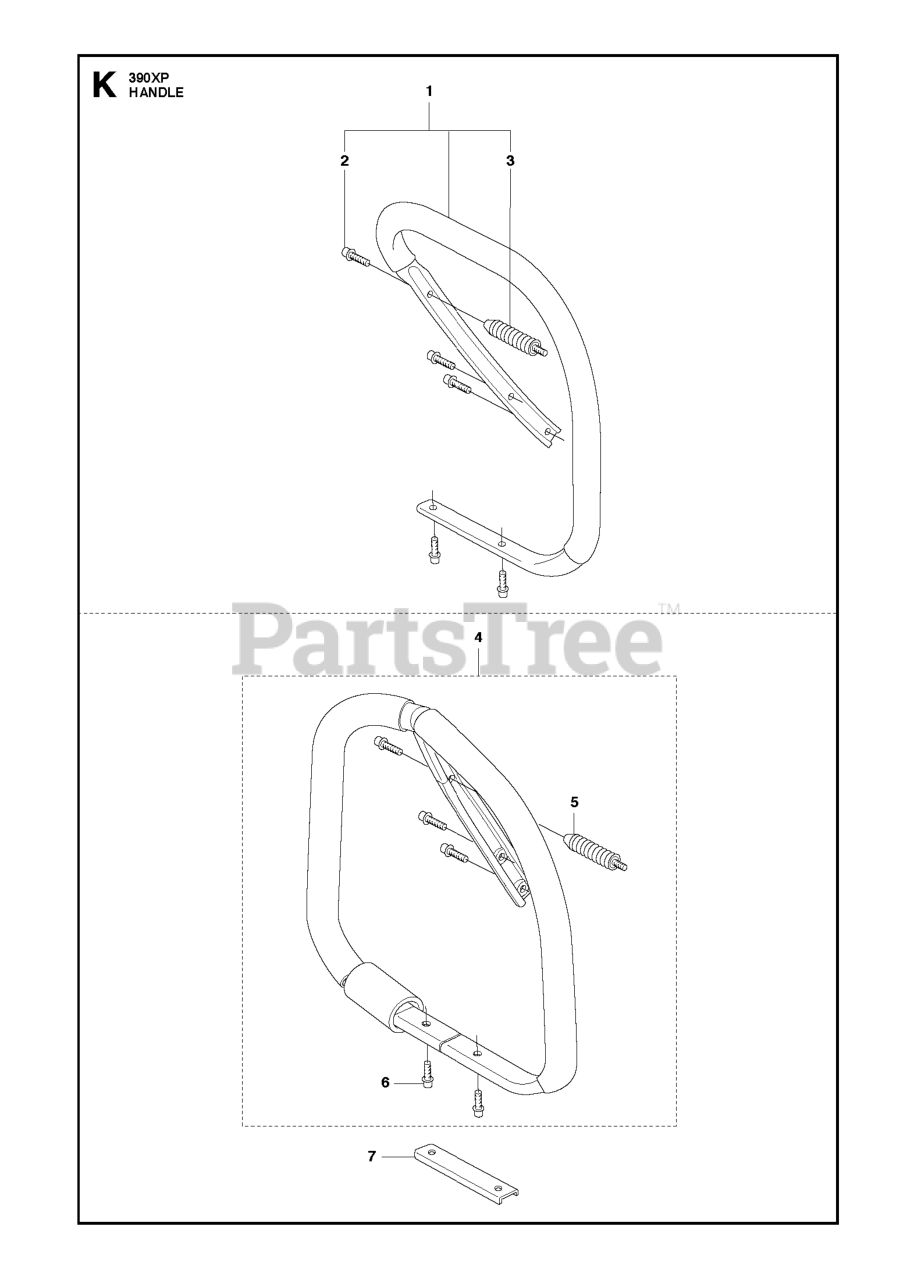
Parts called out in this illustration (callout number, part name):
1	FRONT HANDLE
4	HANDLE
5	VIBRATION ABSORBER
5	SPRING
6	SCREW
7	PLATE
